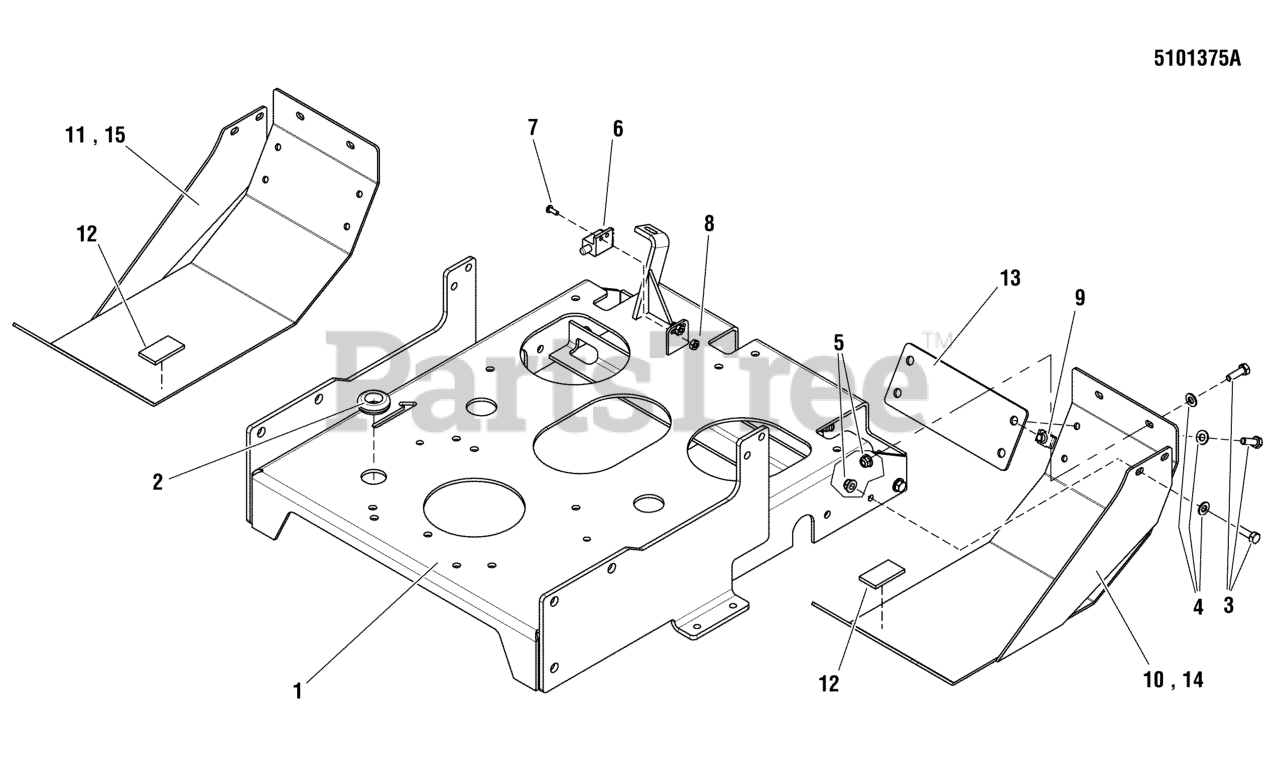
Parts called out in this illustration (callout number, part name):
1	WELD, ENGINE DECK, SNP PRO WB - RED
2	GROMMET, 7/8
3	BOLT, 5/16-18 X 1 GD5 YZ
4	WASHER, 5/16" SAE
5	NUT, 5/16-18 HEX NYLOCK FLANGE
6	SWITCH, PLUNGER, N.O./N.C.
7	SCREW- #10-24 X 1/2 ROUND PHILLIPS
8	NUT, #10-24 HEX
9	BODY CLIP, 5/16-18-7GA MATERIAL
10	WELD, SKID PLATE, LH - RED
11	WELD, SKID PLATE, RH - RED
12	PAD, RUBBER MOUNT, 1/4 MAT
13	PLATE, REAR GUARD - RED
14	WELD, SKID GUARD, LH, CCW36RD
15	WELD, SKID GUARD, RH, CCW36RD
